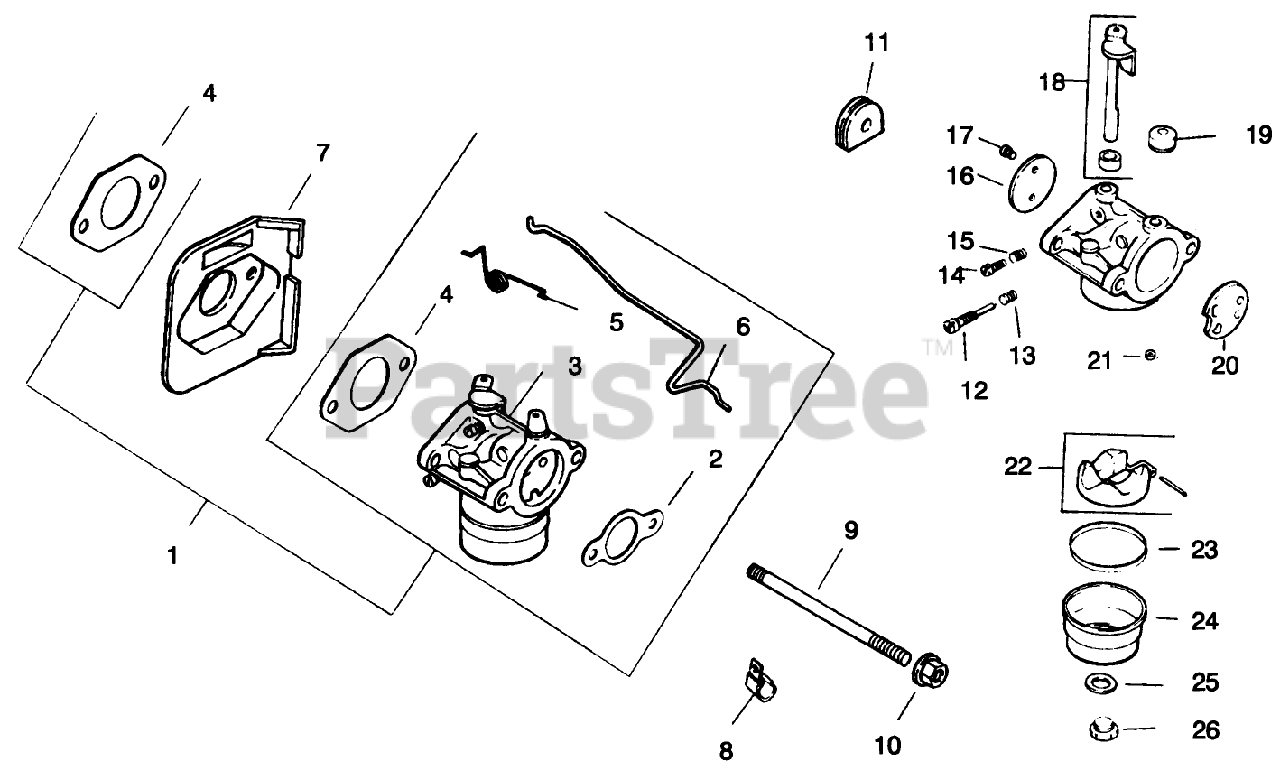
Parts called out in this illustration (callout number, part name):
1	Kit-Carburetor (Incl Ref. #2-6)
2	Gasket-Air Cleaner (Only On: 72042, 72043, 72062, 72063)
3	Carburetor Assembly (Incl Ref. #12-26)
4	Gasket-Carburetor (Only On: 72042, 72063, 72062, 72043)
5	Spring Choke
6	Linkage-Choke (Only On: 72042,72043,72062,72063)
7	Deflector-Heat (Only On: 72042,72043,72062,72063)
8	Clip-Cable (Only On: 72103)
9	Stud M6x1.0x110 (Only On: 72042,72043,72062,72063)
11	Grommet (Only On: 72042, 72063, 72062, 72043)
12	Needle-Idle
13	Spring-Idle Fuel (Only On: 72042, 72063, 72062, 72043)
14	Screw-Idle Speed Adjust (Only On: 72042,72043,72062,72063)
15	Spring-Idle Fuel (Only On: 72042, 72063, 72062, 72043)
16	Plate-Throttle (Only On: 72042,72043,72062,72063)
17	Screw-Throttle Plate (Only On: 72042,72043,72062,72063)
18	Shaft-W/Lever Seal (Only On: 72042, 72063, 72062, 72043)
19	Cap-Choke Lever
20	Plate-Choke
21	Jet-Main
22	Kit-Float (Only On: 72042,72043,72062,72063)
23	Gasket-Bowl (Only On: 72042,72043,72062,72063)
24	Bowl-Fuel (Only On: 72042, 72063, 72062, 72043)
25	Gasket-Bowl Screw (Only On: 72042, 72063, 72062, 72043)
26	Screw-Fuel Bowl (Only On: 72042, 72063,72062, 72043)
